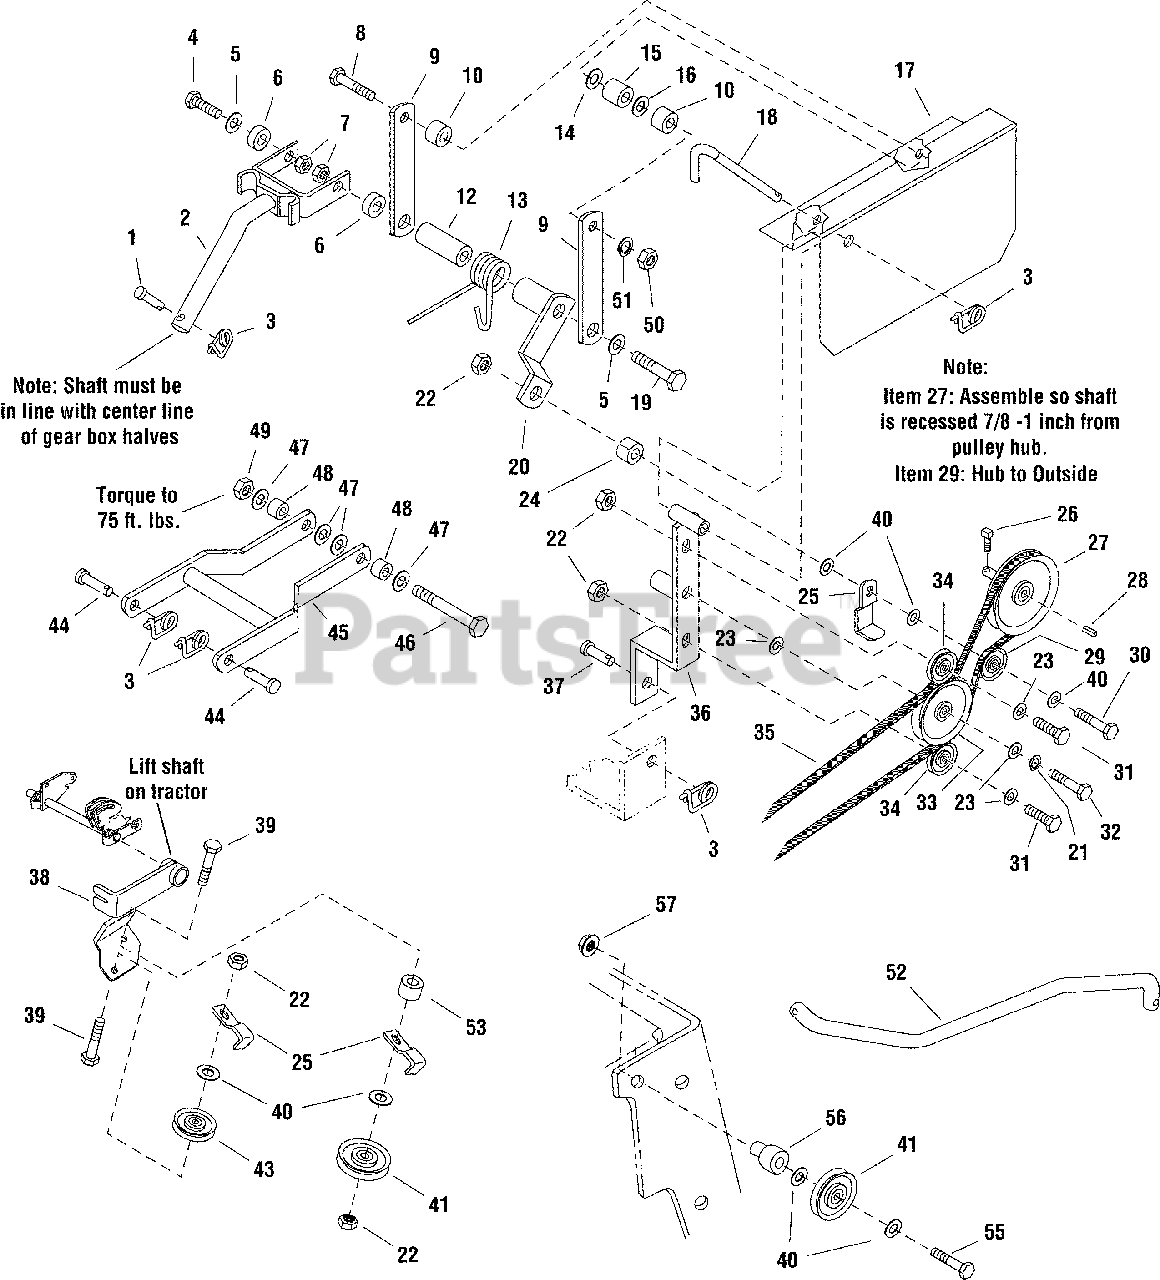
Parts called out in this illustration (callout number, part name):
1	PIN, Round Head Drilled, 3/8 x 2
2	LIFT ASSEMBLY SHAFT
3	SAFETY CLIP
4	CAPSCREW, Hex Head, 7/16-14 x 1-1/4, Black
5	WASHER, 7/16
6	SPACER .452 x .75 x .562
7	NUT, Hex Flange Lock, 7/16-14, Black
8	CAPSCREW, Hex Head, 5/16-18 x 2-3/4, Balck
9	SUPPORT, Rear Belt Guard
10	SPACER
12	SPACER 2 3/16
13	SPRING, Torsion
14	WASHER, Special, Nylon
15	BUSHING, .343" x .750" x 1.060"
16	WASHER, 5/16, Black
17	COVER, Belt
18	ROD
19	CAPSCREW, Hex Head, 7/16-14 x 3-1/2, G8
20	ARM & HUB ASSEMBLY
21	LOCKWASHER, 3/8
22	NUT, Hex, 3/8-16
23	WASHER, 3/8
24	SPACER .39 x 1 x 1.31
25	GUARD, Spring
26	SCREW, Set Square Head, Cup Point, 3/8-16 x 1/2
27	PULLEY, 7.96" OD x .752" ID, w/.562" Groove, w/Hub
28	KEY, Parallel .187 x .187 x 1.25
29	PULLEY, Idler, 2.75" OD x .377" ID x .87 WD
30	CAPSCREW, Hex Head, 3/8-16 x 3-1/2, Black
31	CAPSCREW, Hex Head, 3/8-16 x 1-3/4, Black
32	CAPSCREW, Hex Head, 3/8-16 x 1-1/4, Black
33	PULLEY, Idler, 4" OD x .375" ID x .83" WD
34	PULLEY, Idler, 1.875" OD x .375" ID x .97" WD
35	V-BELT,167.40" Long
36	SHAFT & SUPPORT ASSEMBLY
37	PIN, Round Head Drilled, 3/8 x 1, Black
38	ARM ASSEMBLY, Tiller Idler
39	CAPSCREW, Hex Head, .375-16 x 2-1/4
40	WASHER, 3/8
41	PULLEY, Idler, 4.00" OD x .669" ID x 1WD, w/Bearing
43	PULLEY, 3" OD x .378" ID x .75" WD, w/Bearing
44	PIN, Round Head Drilled, 7/16 x 1-3/4
45	FRAME ASSEMBLY
46	CAPSCREW, Hex Head, 1/2-13 x 5, G8
47	WASHER, 1/2, Black
48	SPACER
49	NUT, Hex Flange Lock, 1/2-13, Black
50	NUT, Hex, 5/16-18, Black
51	LOCKWASHER, 5/16, Black
52	ROD, Diff Lock, 15" Long
53	SPACER
55	CAPSCREW, 3/8-16 x 2-1/2
56	SPACER
57	NUT, Flange, 3/8-16
